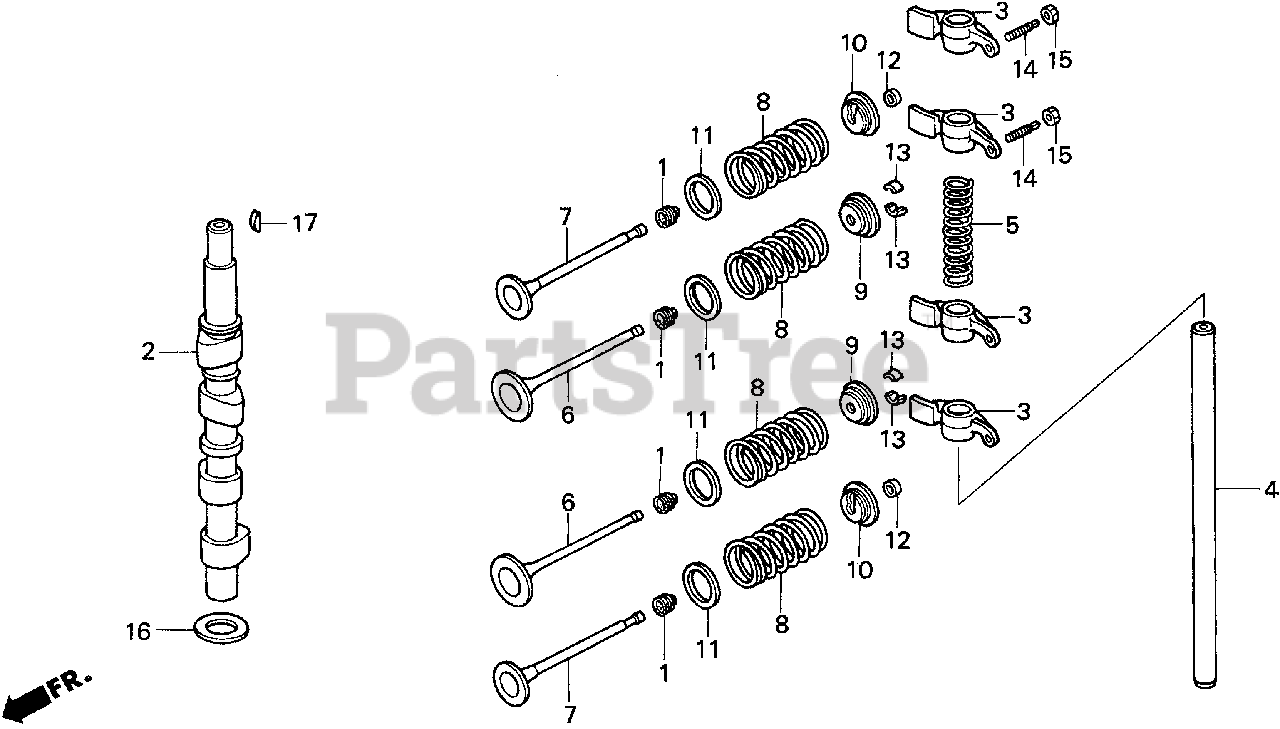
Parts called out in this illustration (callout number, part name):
1	SEAL, VALVE STEM
3	ARM, VALVE ROCKER
4	SHAFT, VALVE ROCKER ARM
5	SPRING, VALVE ROCKER ARM
6	VALVE, IN.
7	VALVE, EX.
8	SPRING, VALVE
9	RETAINER, VALVE SPRING
10	RETAINER, EX. VALVE SPRING
11	SEAT, VALVE SPRING
12	ROTATOR, VALVE
13	COTTER, VALVE (SANKO)
14	SCREW, TAPPET ADJ.
15	NUT, TAPPET ADJ.
16	WASHER, THRUST (16MM)
17	KEY, WOODRUFF (16X12)
